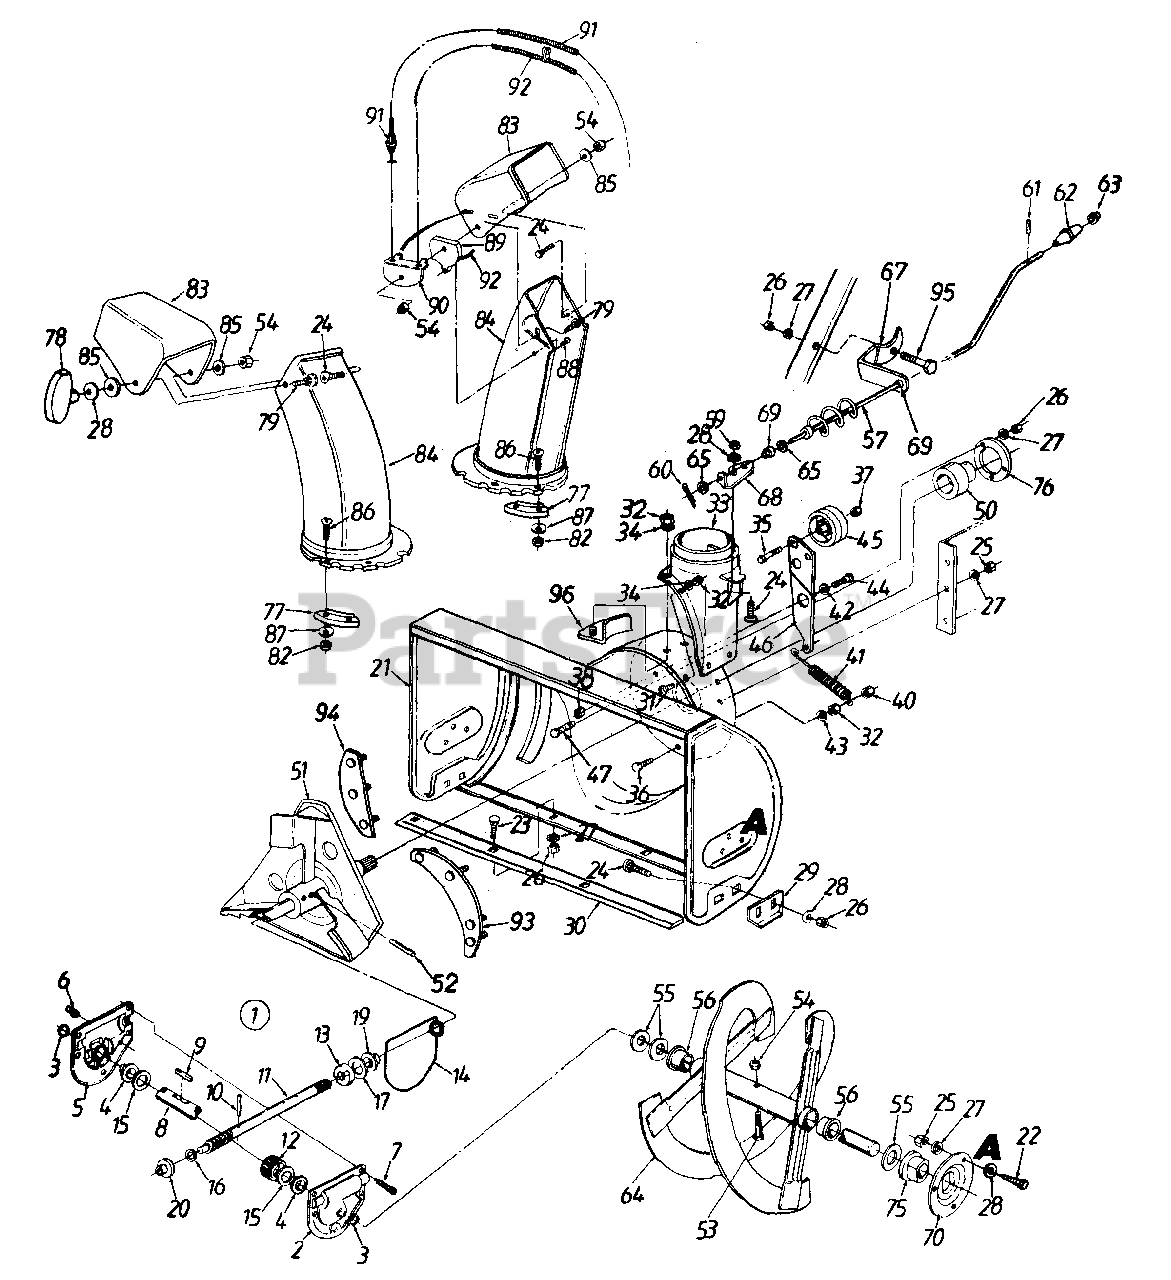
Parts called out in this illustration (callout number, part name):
1	Worm Drive Ass'y. Comp.
2	Reducer Housing - L.H.
4	Flange Bearing .75" I.D.
5	Reducer Housing - R.H.
6	Grease Fitting
7	Hex TT-Tap Scr. 1/4-20 x .75" Lg.
8	24" Auger Shaft
9	#61 Hi-Pro Key 3/16" x 5/8" Dia.
10	Spiral Pin 1.25" Lg.
11	Impeller Shaft
12	Worm Gear
13	Thrust Collar
14	"O"-Ring (Special)
15	Fl-Wash. .76" I.D. x 1.5" O.D.
16	Fl-Wash. .5" I.D. x 1" O.D.
17	Fl-Wash. .76" I.D. x 1.49" O.D.
19	Flange Bearing .75" I.D.
20	Flange Bearing .503" I.D.
21	24" Auger Housing Ass'y.
22	Hex Bolt 5/16-24 x .75" Lg.
23	Carriage Bolt 5/16-18 x .62" Lg.
24	Carriage Bolt 5/16-18 x .75" Lg.
25	Hex Nut 5/16-24 Thd.
26	Hex Nut 5/16-18 Thd.
27	L-Wash. 5/16" I.D.
28	Bell-Wash. .345" I.D. x .88" O.D.
30	24" Shave Plate
31	Truss Mach. Scr. 1/4-20 x .5" Lg.
32	Hex Nut 1/4-20 Thd.
33	Chute Adapter
34	Spring Washer 1/4" I.D.
35	Hex Bolt 3/8-24 x 1.5" Lg. (Gr. 5)
36	Hex Bolt 1/4-20 x .75" Lg. (Gr. 5)
37	Hex Ins. L-Nut 3/8-24 Thd.
38	Hex Top L-Nut 3/8-16 Thd.
40	Hex L-Nut 1/4-20 Thd.
41	Ext. Spring 3.6" Lg.
42	Fl-Wash. 5/8" I.D. x 1.25"
43	L-Wash. 1/4" I.D.
44	Shld. Bolt .625" Dia. x .170" Lg.
45	Fl-Idler 2.75" O.D.
47	Hex Bolt 5/16-18 x 5/8" Lg.
50	Ball Bearing .75" I.D.
51	Blower Fan Ass'y.
52	Spiral Pin 1.5" Lg.
53	Shear Bolt 5/16-18 x 1.5" Lg.
54	Hex Cent. L-Nut 5/16-18 Thd.
55	Fl-Wash. .76" I.D. x 1.49"
56	Flange Bushing .8" I.D.
57	Chute Crank Ass'y.
59	Hex Ins. L-Nut 5/16-18 Thd.
60	Cotter Pin 3/32" Dia. x .75"
61	Roll Pin 1/8" Dia. x .63" Lg.
62	Chute Crank Knob
65	Fl-Wash. .385" I.D. x .62" O.D.
69	Plastic Bushing .38" I.D.
75	Plastic Bearing w/Flats
76	Bearing Housing
77	Chute Flange Keeper
78	Knob Handle Ass'y.
79	Carriage Bolt 5/16-18 x 1.5" Lg.
82	Hex L-Nut 1/4-20 Thd.
83	Upper Chute
84	Lower Chute
85	Fl-Wash. .344" I.D. x 1.125"
86	Truss Mach. Scr. 1/4-20 x .75" Lg.
87	Fl-Wash. 1/4" I.D.
88	Hex AB-Tap Scr. 1/4 x .62" Lg.
89	Cable Guide
91	Chute Control Cable
92	Chute Control Cable w/Clip
96	Chute Reinforcement
